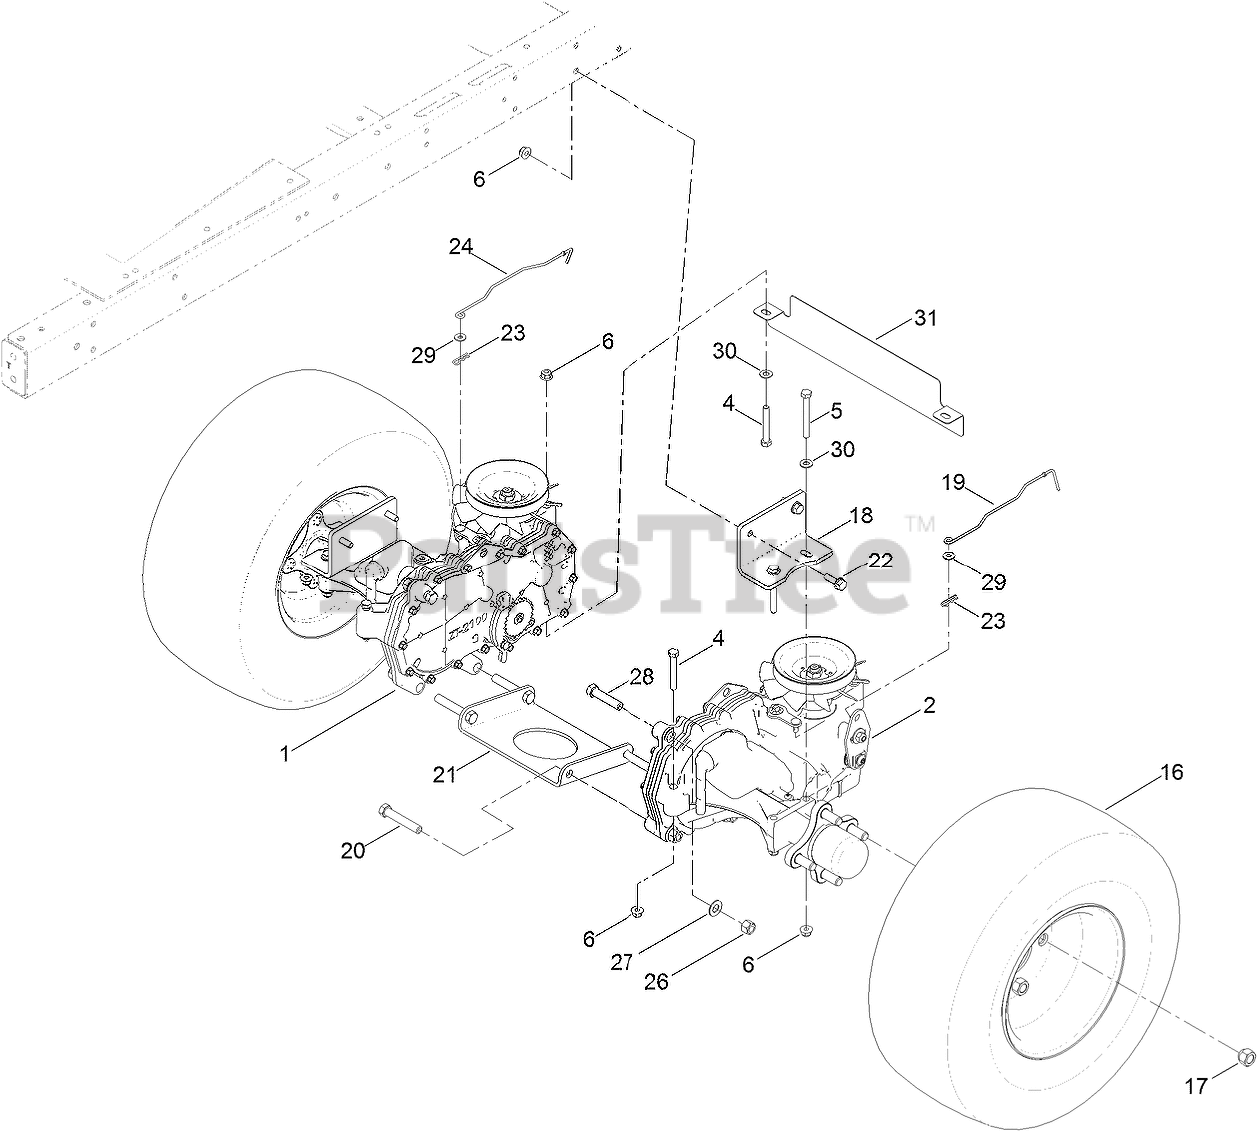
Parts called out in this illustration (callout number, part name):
1	RH HYDRO TRANSAXLE ASM
2	LH HYDRO TRANSAXLE ASM
4	SCREW-HH
5	SCREW-HH
6	NUT-HF, NI
16	2 PLY WHEEL AND TIRE ASM
17	NUT-LUG
18	MOUNT-HYDRO
19	ROD-BYPASS, LH
20	SCREW-HH
21	PLATE-CROSS, HYDRO
22	SCREW-HHF
23	PIN-COTTER
24	ROD-BYPASS, RH
26	NUT-LOCK, NI
27	WASHER-FLAT
28	SCREW-HH
29	WASHER
30	WASHER-PLAIN
31	GUARD REAR, NARROW
